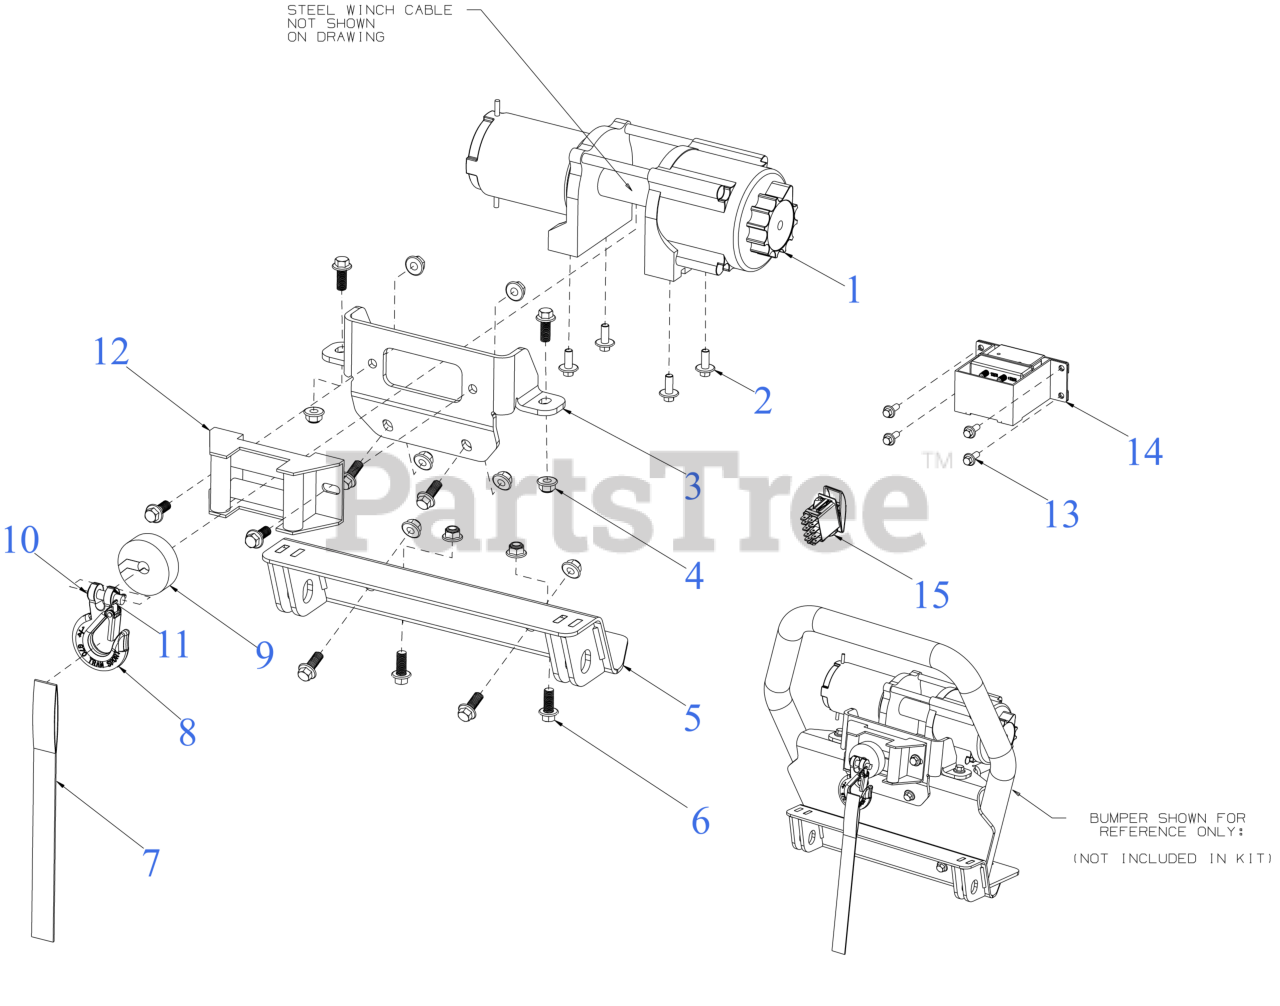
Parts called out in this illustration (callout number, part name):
1	WINCH 3500 LBS
2	HEXAGON FLANGE BOLT M8X20
3	BRKT:RLR
4	LOCK NUT M10X1.25
5	BRKT:HGR:PLOW
6	HEX FLANGE BOLT M10X1.25X20
9	PLASTIC CLASP
10	PIN 9.5X40
11	PIN - COTTER 2X30
12	WINCH GUIDE PULLEY
13	HEXAGON FLANGE BOLT M6X16
14	WINCH RELAY
15	SWITCH - WINCH
